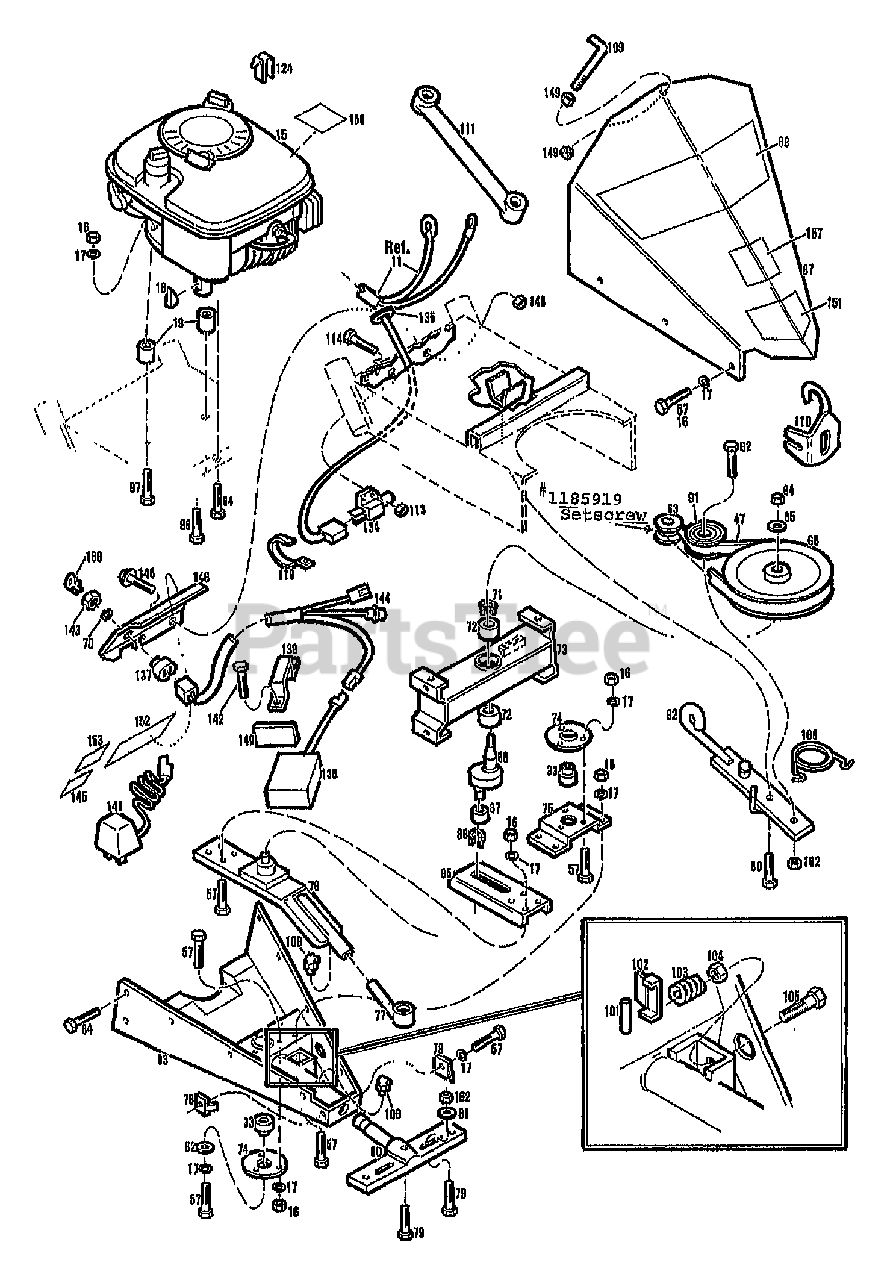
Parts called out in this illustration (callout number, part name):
6	WASHER-FLAT 5/16 SAE
8	SCR
11	HARNESS-OPERATOR INTERLK
15	ENGINE, BRIGGS & STRATTON, 3.5HP STD. #121782-0273-01 (MODEL 34032)
15	ENGINE, BRIGGS & STRATTON, 4HP STD. #122782- 0188-01 (MODEL 34033)
15	ENGINE, BRIGGS & STRATTON, 5HP STD. #126782- 0129-01 (MODEL 34034)
15	ENGINE, BRIGGS & STRATTON, 5HP STD. #126787- 0130-01 (MODEL 34035)
16	NUT-HEX 5/16-18
17	WASHER-LK .312 INT TOOTH
18	KEY-WOODRUFF .156X.625
19	SPACER-ENGINE
21	CENTER LOCK NUT, 5/16-18
33	INSERT-BEARING
42	NUT-HFLK 3/8-16
57	SCR-HHC 5/16-18X.75 GR 5
62	SCR-HH 3/8-16X1.5 G5
63	PULLEY-ENGINE (SER SCREW #1185919)
64	NUT-HEX 5/8-18
65	WASHER-1.305X.649X.098
66	SHEAVE-ECCENTRIC
67	HOOD W/DECALS (INCL. 151 & 157)
68	DECAL-LOGO T/B SICKLEBAR
71	RING-RETAIN EXT .984 ID
72	BEARING-BALL
73	ASSM-HOUSING
74	RETAINER-BEARING
75	SUPT-BEARING UPPER
76	ASSM-ARM ECCENTRIC
77	KIT-KNIFE HEAD & PITMAN
78	STOP-CUTTER BAR
79	SCR-HFLK 3/8-16X1.00
80	ASSM-MOUNTING BRKT
81	WASHER-.986X.437X.083
82	WASHER-FLAT 5/16 SAE
83	ASSM-HOUSING
84	SCR-HFLK 5/16-18X.75
85	ASSM-ARM ECCENTRIC
86	RING-RETAIN EXT .669 ID
87	BEARING-ECCENTRIC
88	SHAFT-ECCENTRIC
90	SCR-SHOULDER
91	IDLER-SHEAVE 3" X 1"
92	KNIFE CLUTCH ARM WELDMENT
94	SCR-HH 5/16-18X3.0
96	SCR-HH 5/16-18X4.0 G5
97	SCR 5/16-18X3.00
101	PIN-.375X1.5
102	PIN-RETAIN
103	SPRING-COMPRESSION
104	NUT-HT/LK
105	SCR-HH 7/16-20X1.25 G5
108	FITTING-GREASE 90 DEGREE
109	HOOK-UPPER .25
110	ASSM-HOOK
111	DIVERTER-WEED BUNGI
113	NUT W/LKWASHER 10-24
114	SCR-HHS 10-24X.625
119	TIE-CABLE NYLON BLACK
124	CLIP-CABLE
134	SWITCH
135	GROMMET
137	SWITCH-EL IGNITION {34035}
138	KIT-BATTERY REPLACE {34035
139	CLAMP-BATTERY {34035}
140	PAD-BATTERY {34035}
141	CHARGER-ELEC BATTERY {34035}
142	SCR-HFLK 1/4-20 X .375 {34035}
143	NUT (IGNIT SWITCH)
144	HARNESS-STARTING {34035}
145	DECAL-ELEC START ENG {34035}
146	PLATE W/DECALS (INCL. 145, 152 & 153)
148	SCR-HFLK 1/4-20X.50
149	NUT-HF/LK 1/4-20
151	DECAL-OPEI CAUTION
152	DECAL-WARN.OPER.INST
153	DECAL-AMERICAN LEGEND-SM
157	DECAL-DNG SHARP CUT BLADE
158	DECAL-WARN.HOT SURFACES
162	NUT-H/LK 3/8-16
166	SPRING-TORSION
168	KEY-IGNITION
